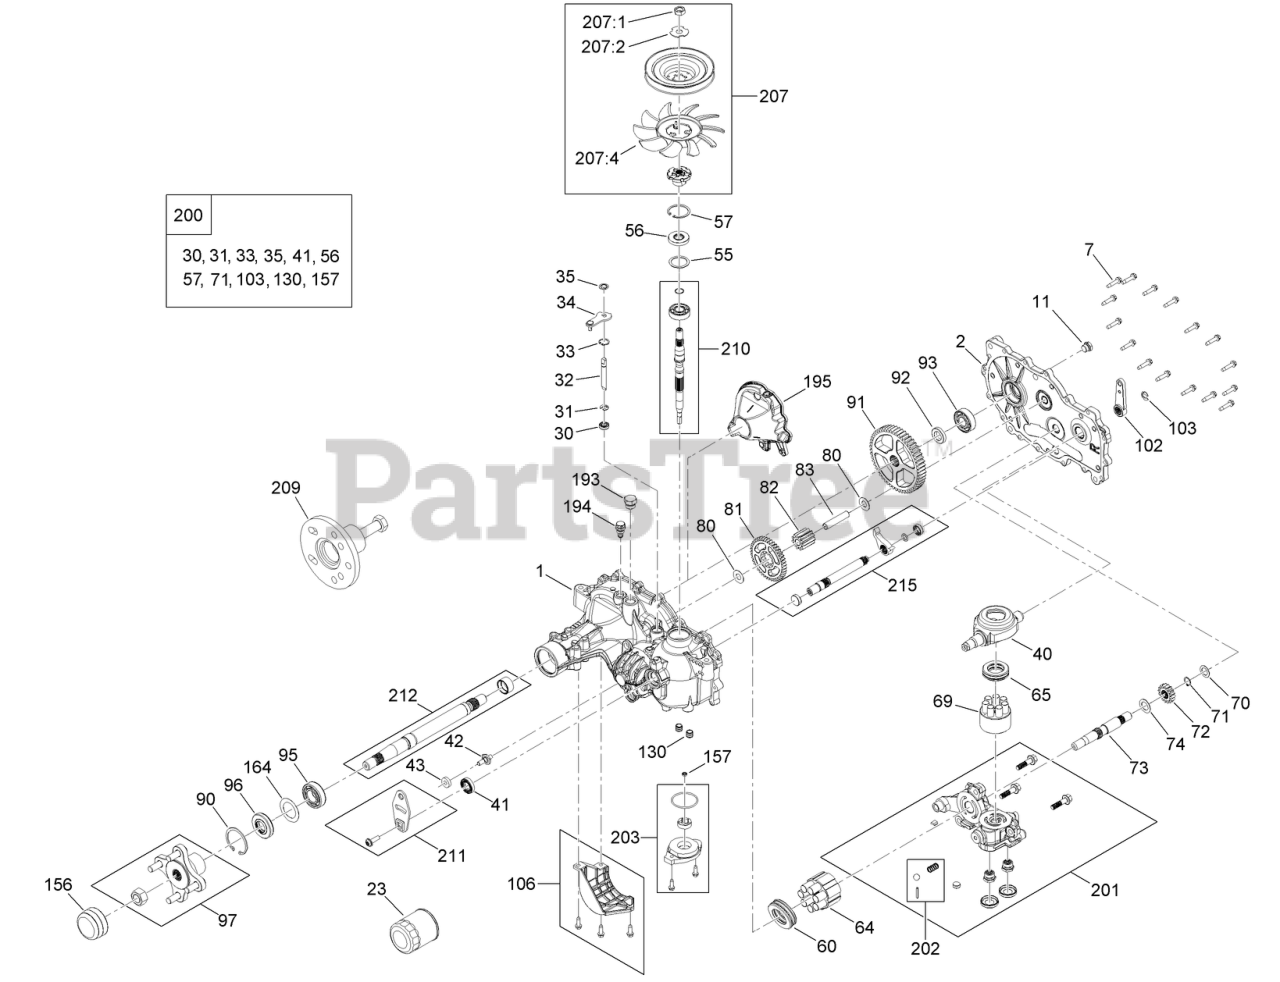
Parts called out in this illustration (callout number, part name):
1	RH MAIN HOUSING KIT
2	RH SIDE COVER KIT
7	SCREW-HHF
23	ELEMENT-OIL FILTER, HYD
30	SEAL-LIP
31	RING-RETAINING, EXTERNAL
32	ROD-BYPASS
33	RING-RETAINING, INTERNAL
35	RING-RETAINING, EXTERNAL
40	SWASHPLATE-TRUNNION
41	SEAL-LIP
43	PUCK-FRICTION
55	SPACER
56	SEAL-LIP
57	RING-RETAINING
60	BEARING-THRUST
64	CYLINDER BLOCK ASM KIT
65	BEARING-THRUST
69	PUMP BLOCK ASM
70	WASHER-FLAT
71	RING-RETAINING
72	GEAR-14T
73	SHAFT-MOTOR
74	WASHER
80	WASHER
81	GEAR-45T
82	GEAR-11T
83	PIN-JACKSHAFT
90	RING-RETAINING
91	GEAR-54T
92	SPACER
93	BEARING KIT
95	BEARING-BALL
97	HUB KIT
102	HANDLE-BRAKE
103	RING-RETAINING, EXT
106	FILTER GUARD KIT
130	TUBE-CHARGE
156	COVER-NUT, AXLE
157	GEROTOR SEAL KIT
164	SPACER
194	BREATHER FITTING ASM
195	RH INTERNAL EXPANSION TANK ASM
200	SEAL KIT
201	RH CHARGE CENTER SECTION KIT
202	CHARGE RELIEF KIT
203	CHARGE KIT
207	FAN AND PULLEY KIT
207:1	NUT-HJ
207:2	WASHER-SLOTTED
207:4	FAN 7.0 X 10 BLADE
210	INPUT SHAFT KIT
211	CONTROL ARM KIT
212	AXLE SHAFT KIT
215	INBOARD KIT
